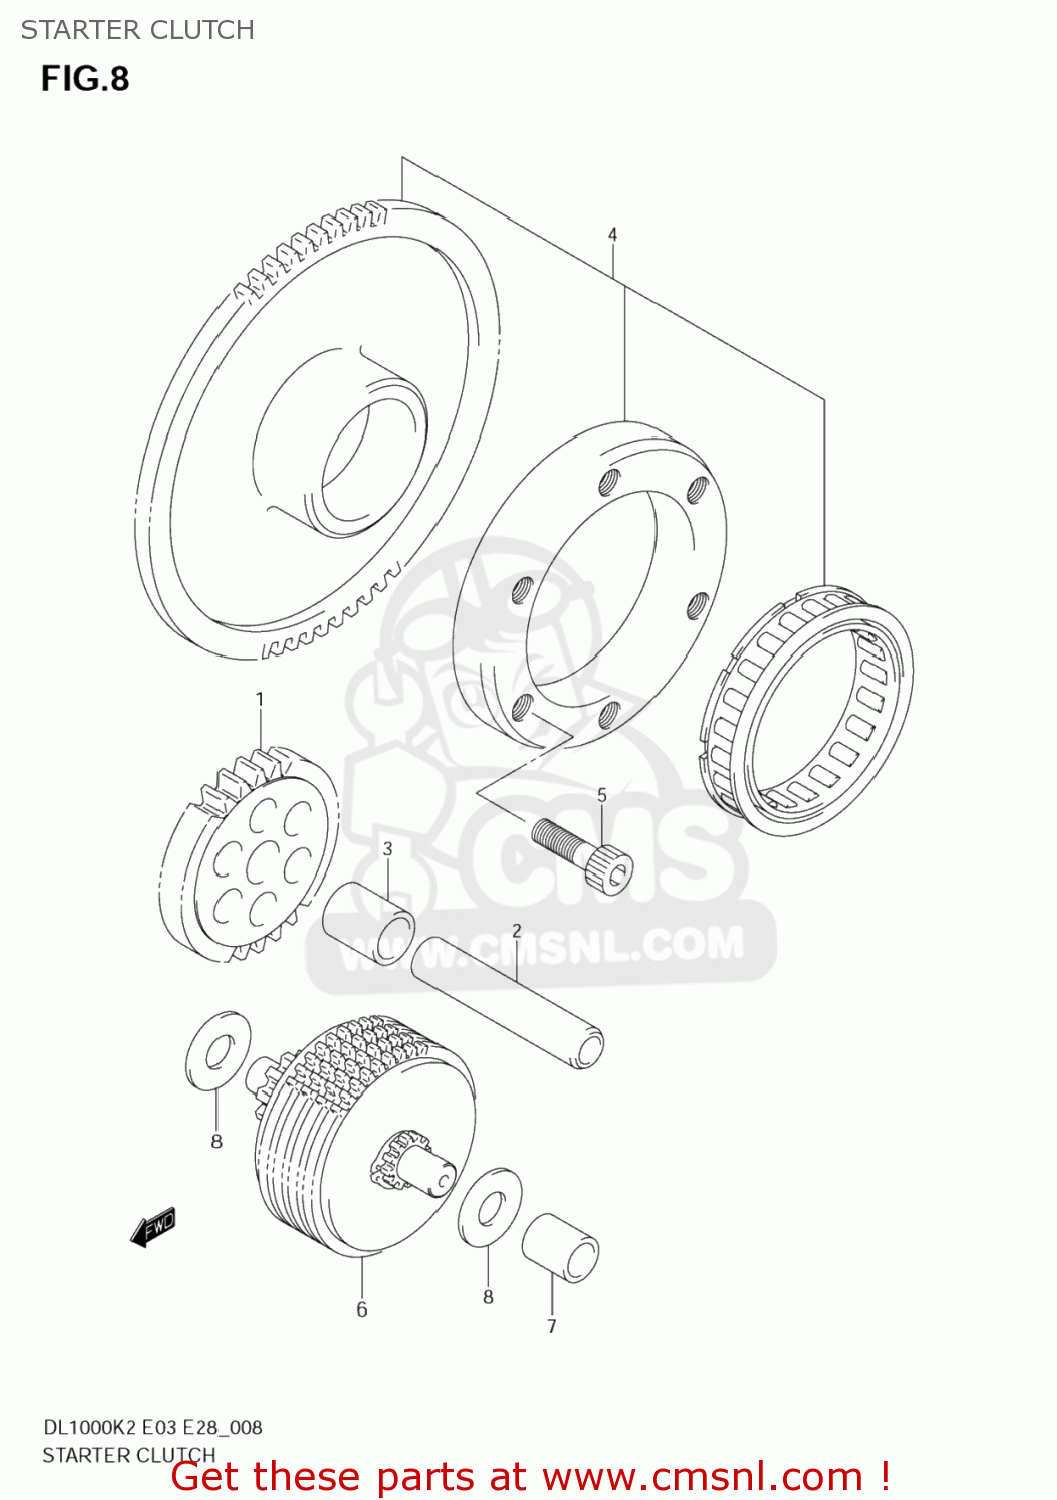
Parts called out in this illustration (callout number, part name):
1	GEAR,STARTER IDLE NO.2
2	PIN(7X12X50.5)
3	SPACER(12.5X19X17.5)
4	CLUTCH SET,STARTER
5	BOLT(8X20)
6	LIMITER ASSY, STARTER IDLE
7	BUSH,LIMITER GEAR SHAFT
8	WASHER
